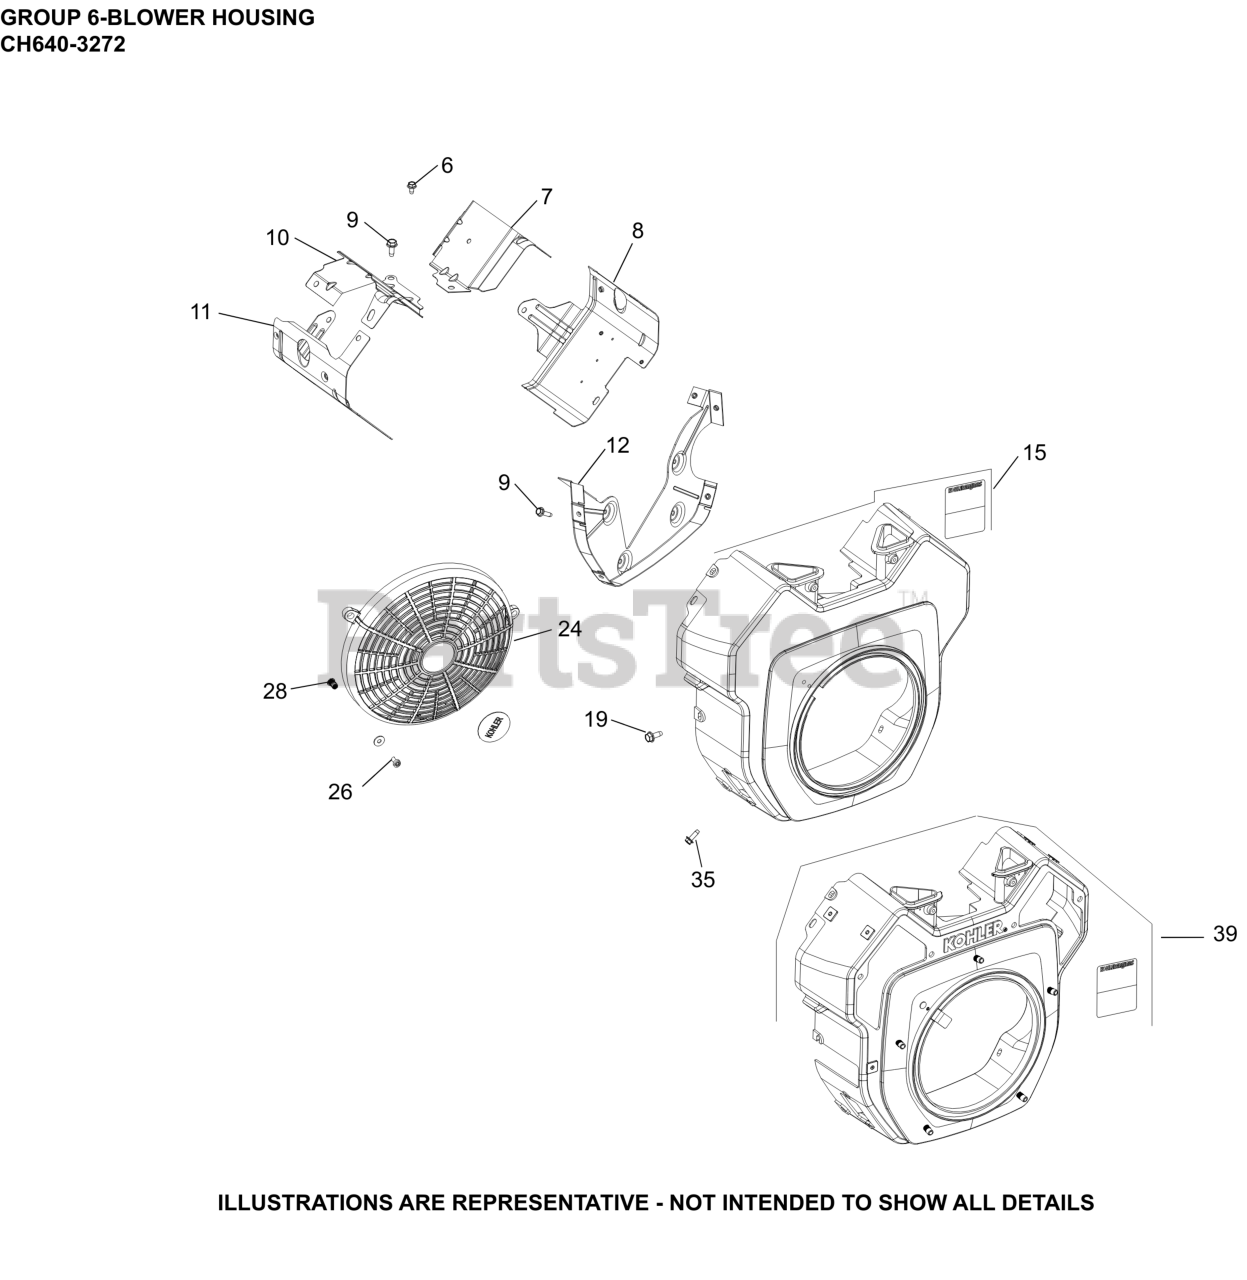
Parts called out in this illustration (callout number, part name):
6	SCREW, THREAD FORMING
7	BAFFLE, VALLEY #1 CYLINDER
8	KIT, CYL BAFFEL #1 SIDE
9	SCREW, THREAD FORMING
10	BAFFLE, VALLEY #2 CYLINDER
11	BAFFLE, LEFT BARREL
12	KIT, BACKING PLATE
15	HOUSING, BLOWER
19	SCREW, THREAD FORMING
24	KIT, FIXED GUARD
26	SCREW, SEMS
28	INSERT, THREADED (M5)
35	SCREW, THREAD FORMING
39	KIT, BLOWER HOUSING
